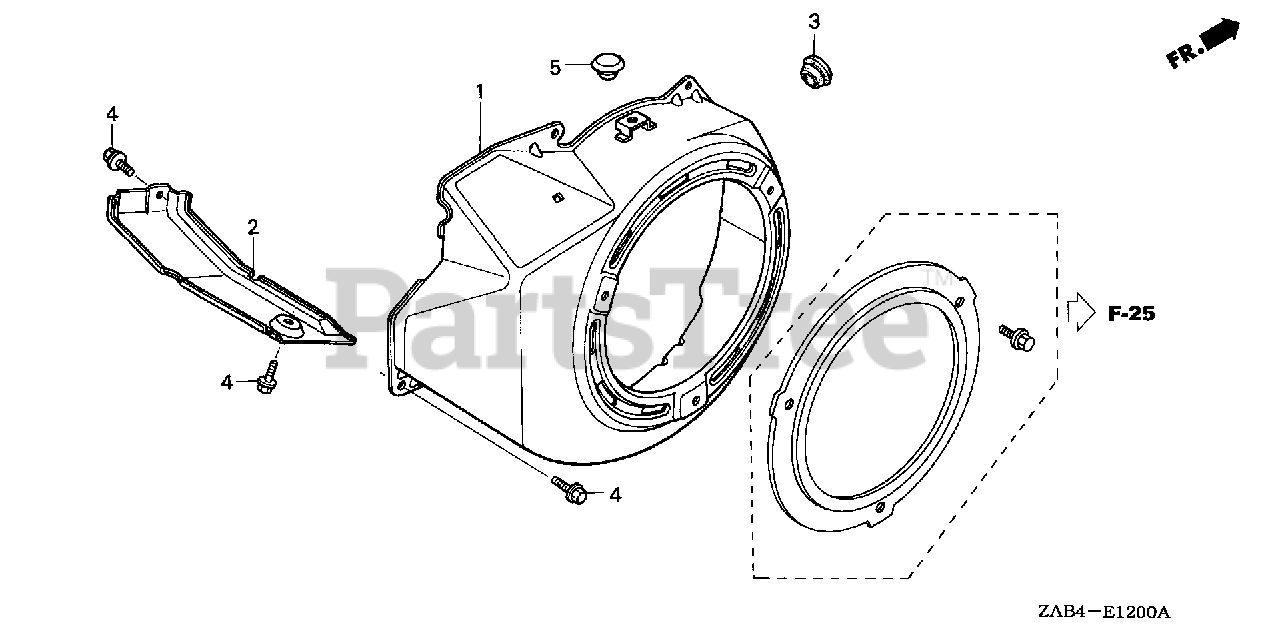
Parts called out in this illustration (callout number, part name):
1	COVER, FAN *NH1* (BLACK)
3	GROMMET, DRAIN HOLE
4	BOLT, FLANGE (6X12) (CT200)
5	PLUG, HOLE
